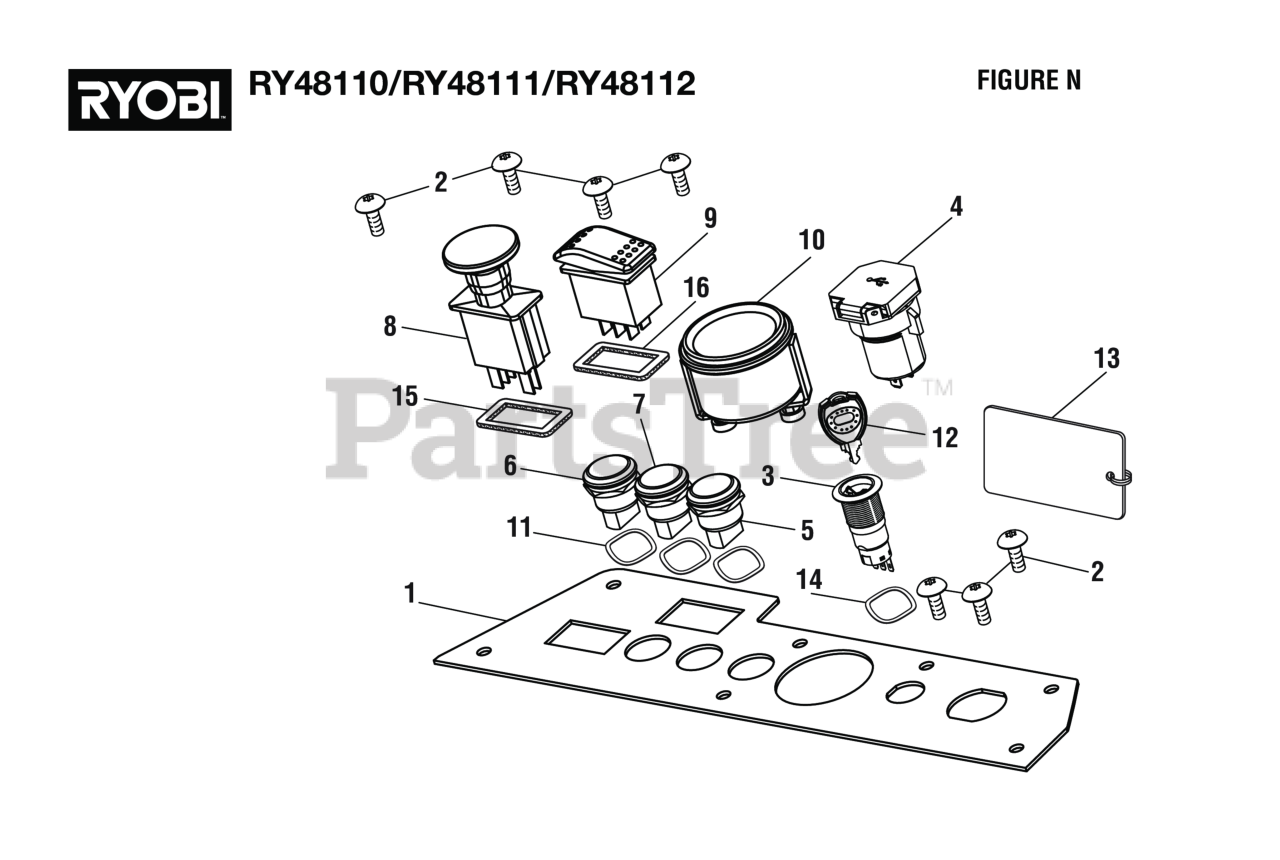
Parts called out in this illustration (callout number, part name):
1	Face Plate
2	Screw (M6 x 10 mm, Soc. Button Hd.)
3	Switch Key Module
4	USB Module
5	Light Switch
6	Cruise Button
7	Reverse Mow Operation Button
8	Power Take Off Button (PTO)
9	Toggle Switch
10	Gauge Module
11	Wavy Washer
13	Watch For Kids, Keychain Label
14	Wavy Washer
15	Rubber Gasket
